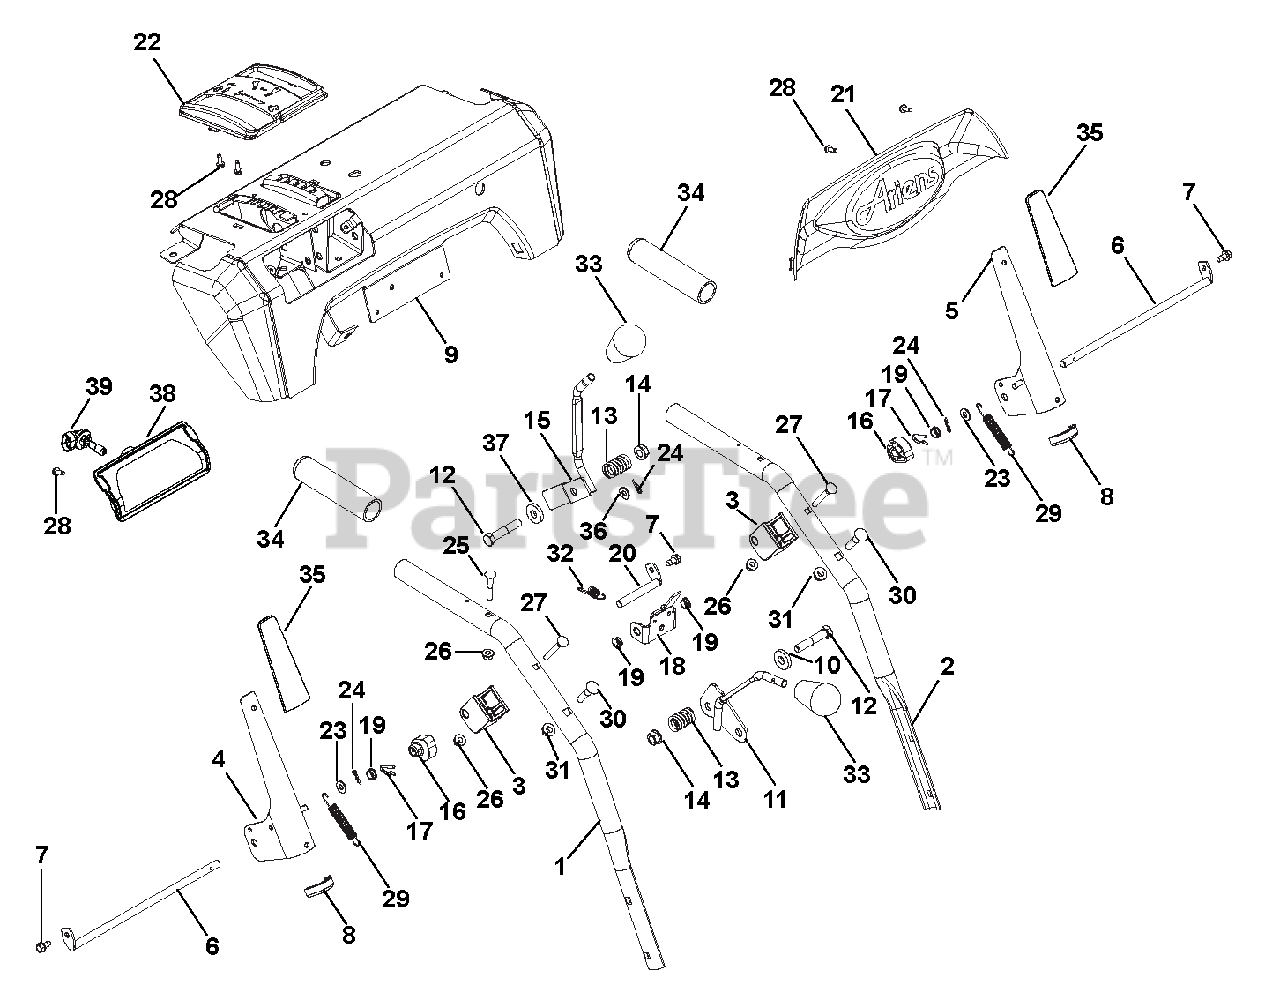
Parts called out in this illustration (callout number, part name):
1	HANDLEBAR, UPPER - RH
1	HANDLEBAR, UPPER RH W/HW
2	HANDLEBAR, UPPER - LH
2	HANDLEBAR, UPPER LH W/HW
3	BLOCK, CLUTCH PADDLE
4	LEVER, CLUTCH-RH
5	LEVER, CLUTCH-LH
6	ROD, PADDLE MOUNT - PRO
7	SCR-TAP .25-20X.50 HWH TR YWZ
8	EDGING, CLUTCH PADDLE - 2.00"
9	CTRL PANEL W/DECAL,CRK HW CLKR
9	CTRL PANEL W/DECAL, QT HW ATC
9	CTRL PANEL W/DECAL, CRNK CLCKR
9	CTRL PANEL W/DECAL, CRNK TRACK
9	CONTROL PANEL W/DECAL, CRANK
9	CONTROL PANEL W/DECAL,CRANK,HW
9	CTRL PANEL W/DECAL, CRANK ATC
9	CTRL PANEL W/DECAL, CRNK TK HW
10	WSHR-FL-STL .406X1.00X.188 YWZ
11	WELDMENT, CONTROL LEVER(SHIFT)
12	@BLT-HEX .38-16X2.00 GR5 YWZC
13	SG-COMP .125X.781X1.250
14	@NUT-LK-TOP-FLG .38-16 YWZC
15	WELDMENT, CONTROL LEVER (DEFL)
16	CAM, INTERLOCK
17	PIN, SPRING CLIP
18	BRACKET, INTERLOCK ARM
19	BUSHING, POLYLINER-.38 SNAPIN
20	ROD, PIVOT - INTERLOCK
21	DASH BEZEL, ARIENS LOGO - PRO
22	BEZEL, SHIFT
23	@WSHR-FL-STL.281X.62X.065 YWZC
24	PIN-HAIR INT .06X.18X.77
25	BLT-RDHDXLSQNK.25-20X1.25 G5ZC
26	@NUT-LK-TOP-FLG .25-20 YWZC
27	BLT-RDHDXLSQNK .25-20X2.0 G5YZ
28	SCR-TAP #10X.50 BOSS INDHXHD
29	SPRING, EXTENSION
30	@BLT-RDHDSQNK .31-18X1.50 G5YZ
31	@NUT-LK-TOP-FLG .31-18 YWZC
32	SPRING-EXT .047X.438X1.45
33	KNOB,SOFT TEARDROP,PUSH-ON GRY
34	HANDLE GRIP
35	CLUTCH PADDLE SLEEVE - GRAY
36	BSHG-SLV .265X.500X.219
37	WSHR-FL-STL .380X1.50X.062 YWZ
38	HEADLIGHT ASSY, HALOGEN 20W
39	BULB, LIGHT-HALOGEN 20W
